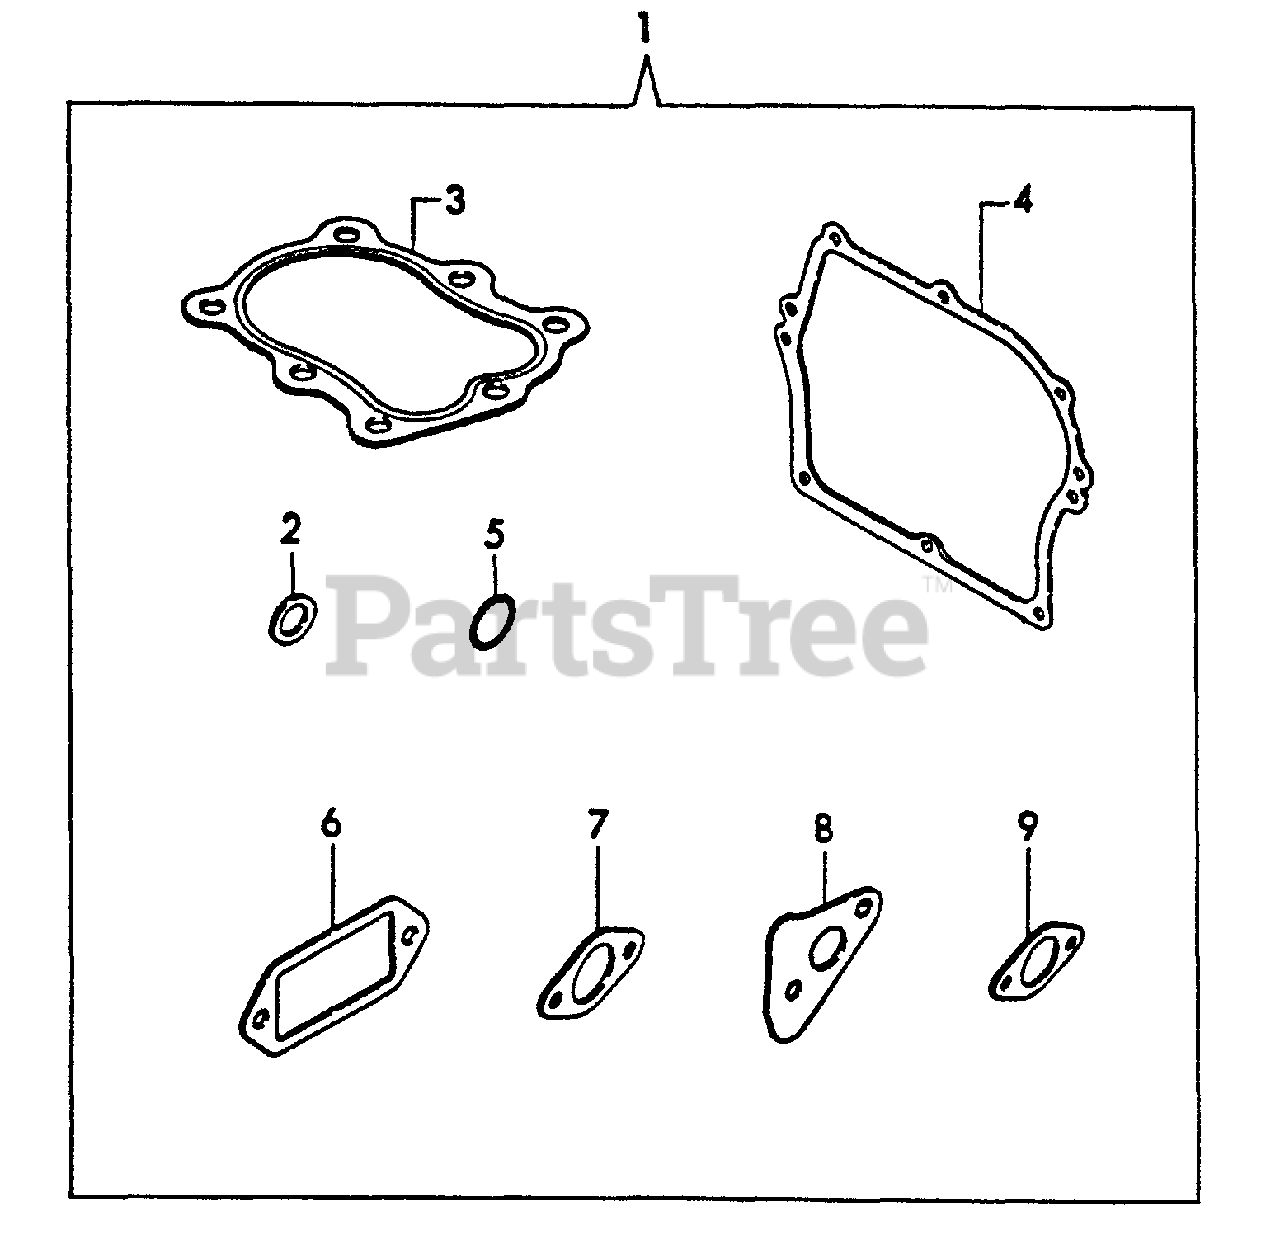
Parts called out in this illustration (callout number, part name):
1	GASKET KIT
2	GASKET
3	GASKET, CYLINDER
4	GASKET
5	O-RING - 18
6	GASKET
7	GASKET, INTAKE
8	GASKET, EXHAUST
9	GASKET, EXHAUST
